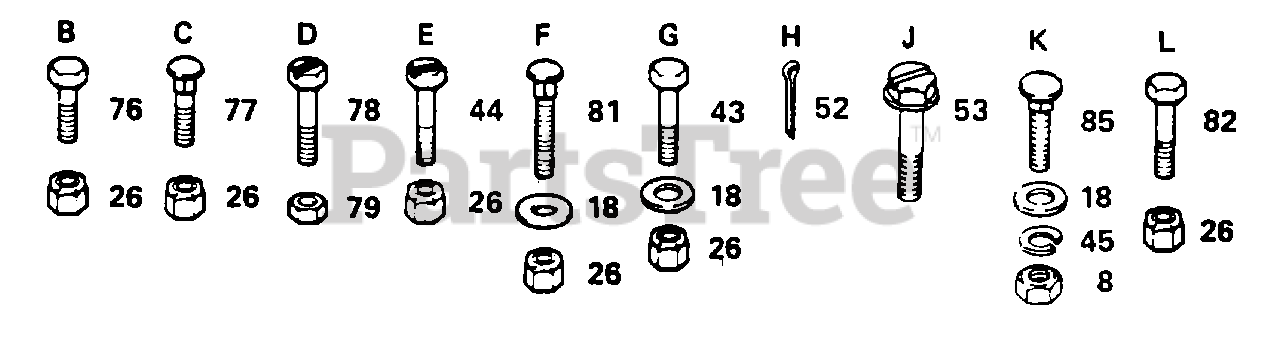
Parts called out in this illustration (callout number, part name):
8	NUT.HEX.3/8-16UNC
18	WASHER
45	LOCKWASHER
53	SCREW
76	BOLT
77	BOLT
78	SCREW
81	BOLT
82	BOLT
